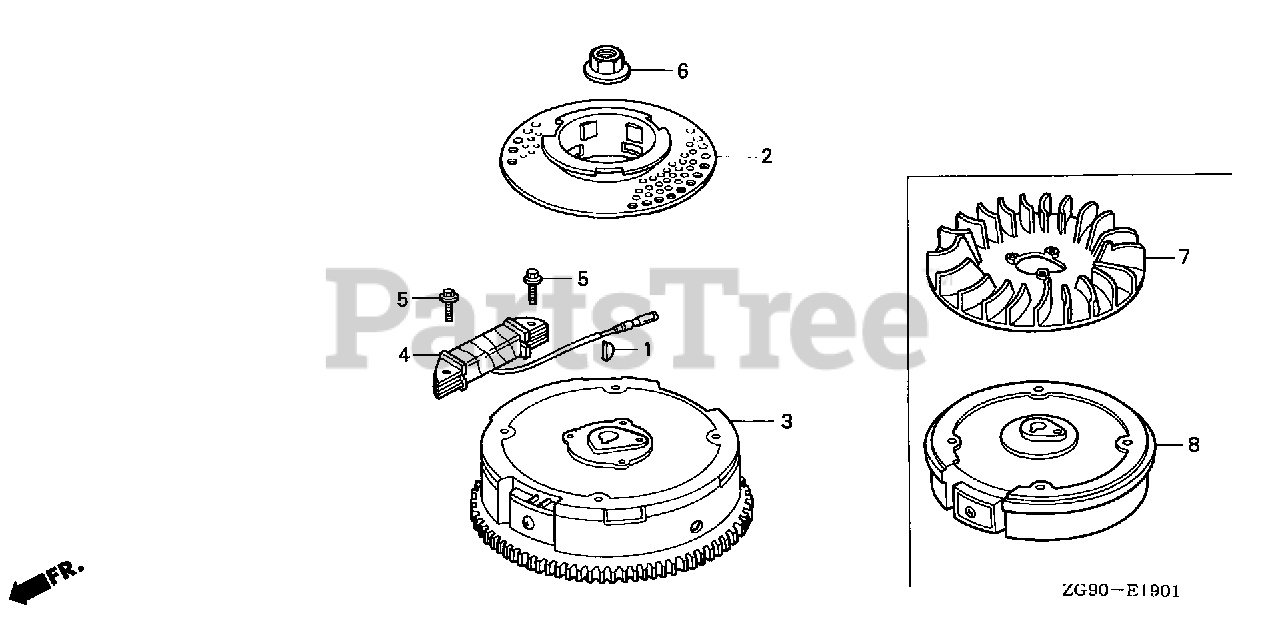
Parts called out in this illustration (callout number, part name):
1	KEY, SPECIAL WOODRUFF (25X18)
6	NUT, SPECIAL (14MM)
7	FAN, COOLING
8	FLYWHEEL
